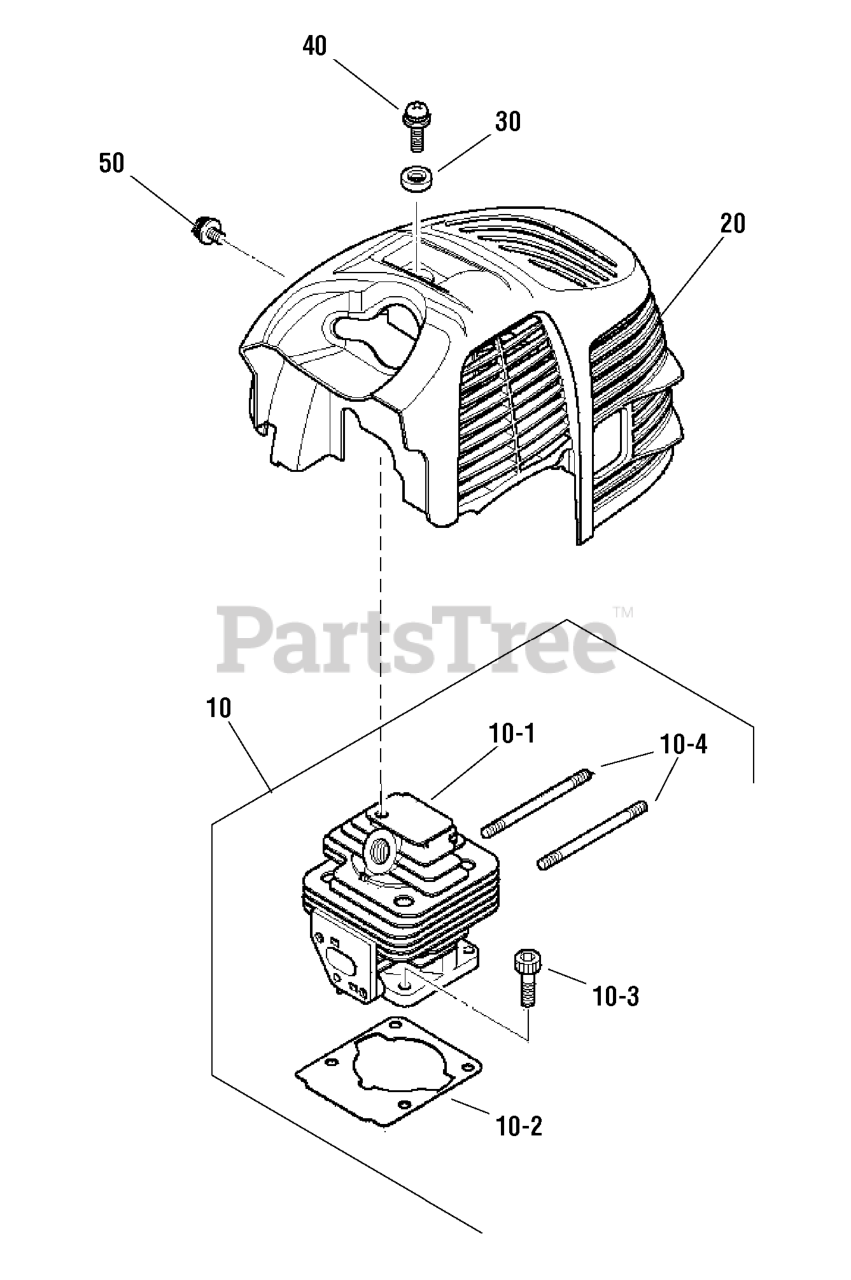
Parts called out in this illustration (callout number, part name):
10	CYLINDER ASSEMBLY
10-1	CYLINDER
10-2	GASKET, Cylinder
10-3	BOLT
10-4	BOLT
20	COVER, Top
30	WASHER
40	SCREW & WASHER
50	SCREW & WASHER
